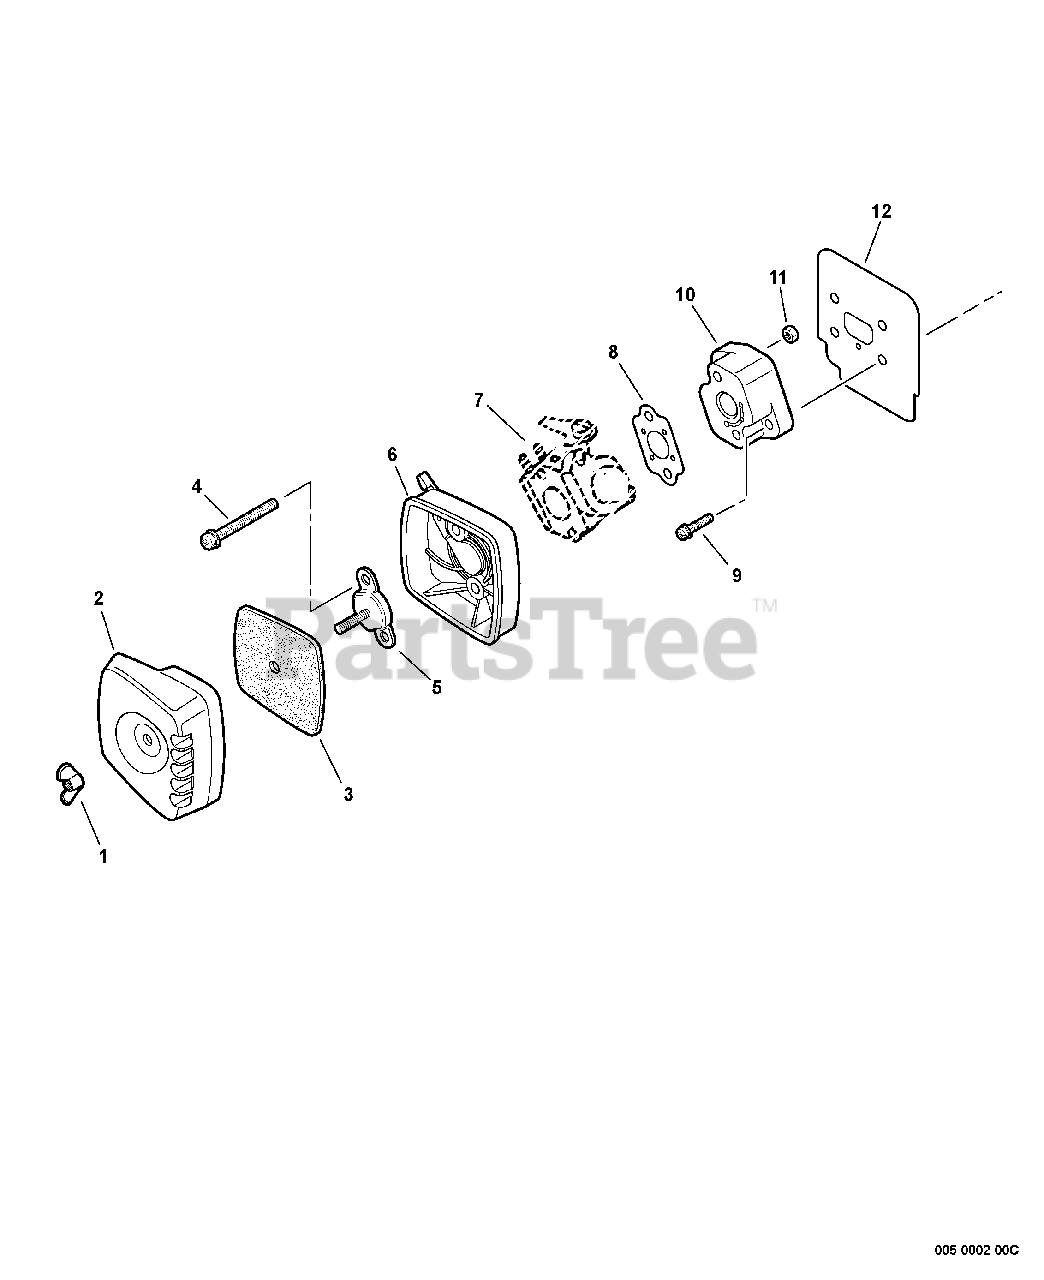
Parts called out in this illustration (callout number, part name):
1	WINGNUT - 6
2	COVER, AIR FILTER - BLACK
3	FILTER, AIR
4	SCREW - 5X65
5	PLATE, PREVENT
6	AIR FILTER CASE KIT - BLACK
7	CARBURETOR
8	GASKET, INTAKE
9	SCREW - 5X20
10	INSULATOR, INTAKE
12	SHIELD, INTAKE
